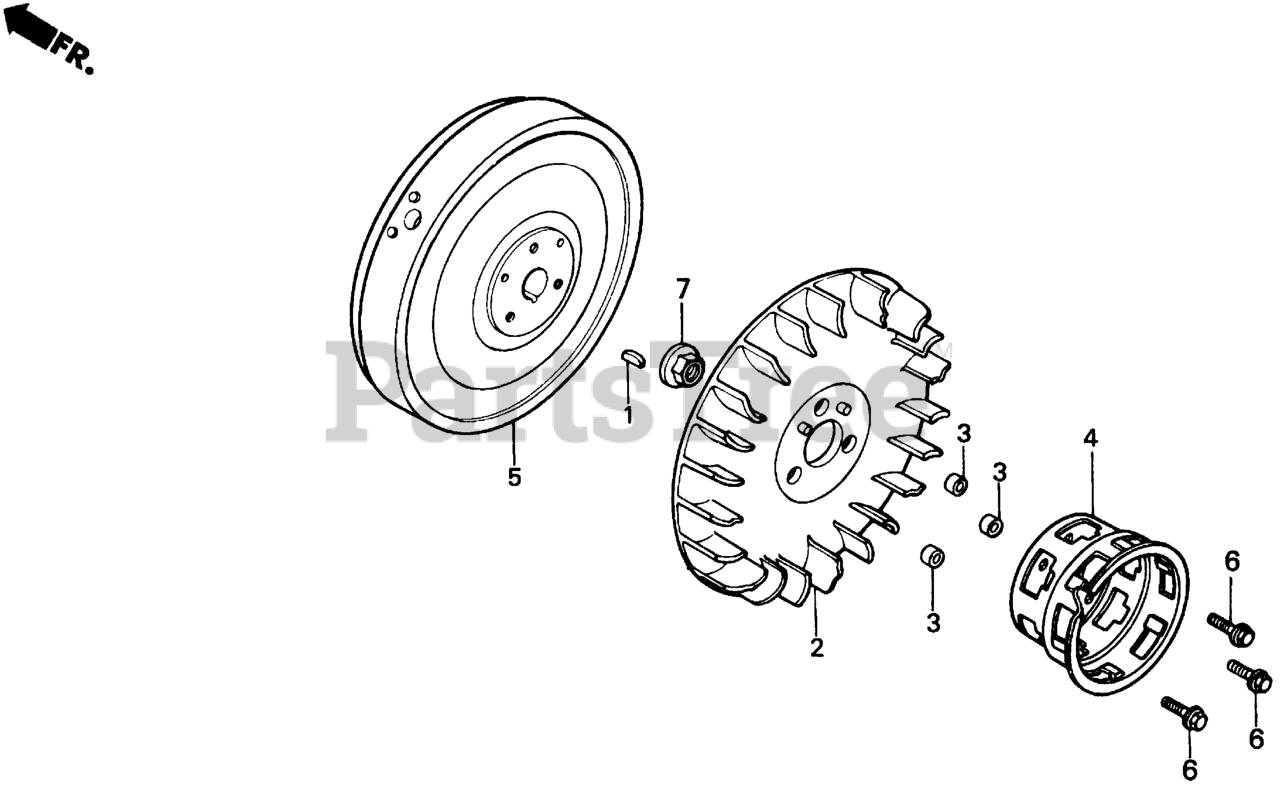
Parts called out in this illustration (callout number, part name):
1	KEY, SPECIAL WOODRUFF (25X18)
2	FAN, COOLING
3	COLLAR, FAN
4	PULLEY, STARTER
5	FLYWHEEL
6	BOLT, FLANGE (6X16)
7	NUT, SPECIAL (16MM)
